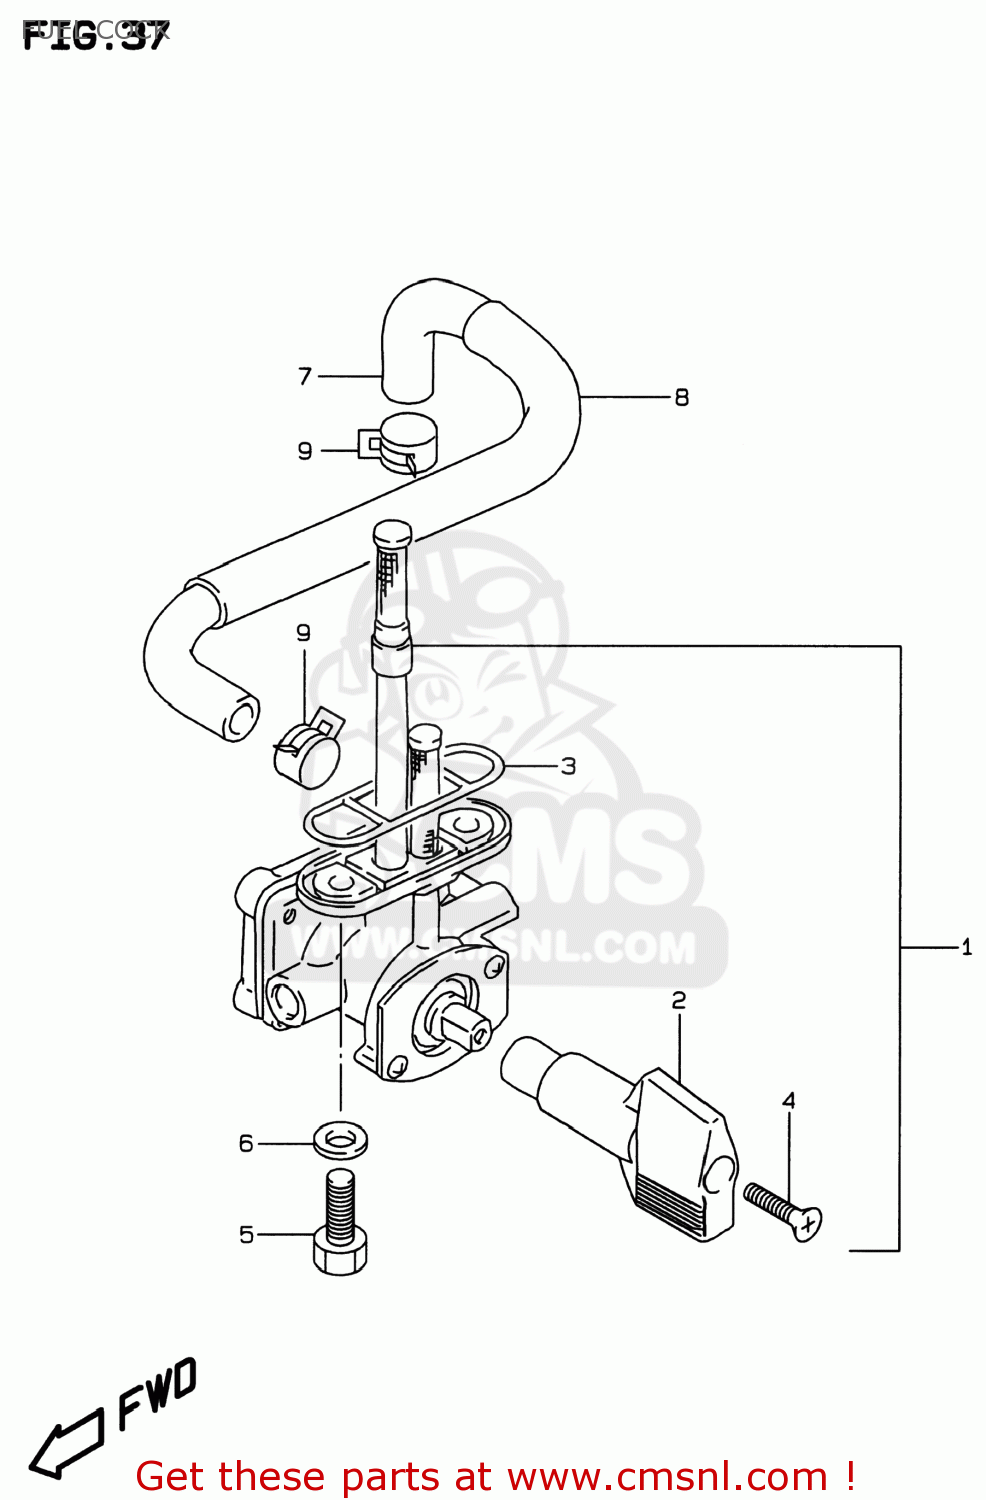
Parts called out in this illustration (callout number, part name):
1	COCK ASSEMBLY,FUEL
2	LEVER,FUEL COCK
3	GASKET,JOINT (NAS)
4	SCREW
5	BOLT(6X20)
6	GASKET(6.4X11.5X0.8) (NAS)
7	HOSE(7X12X600)
8	PROTECTOR(14.5X15.5X600)
9	CLIP
